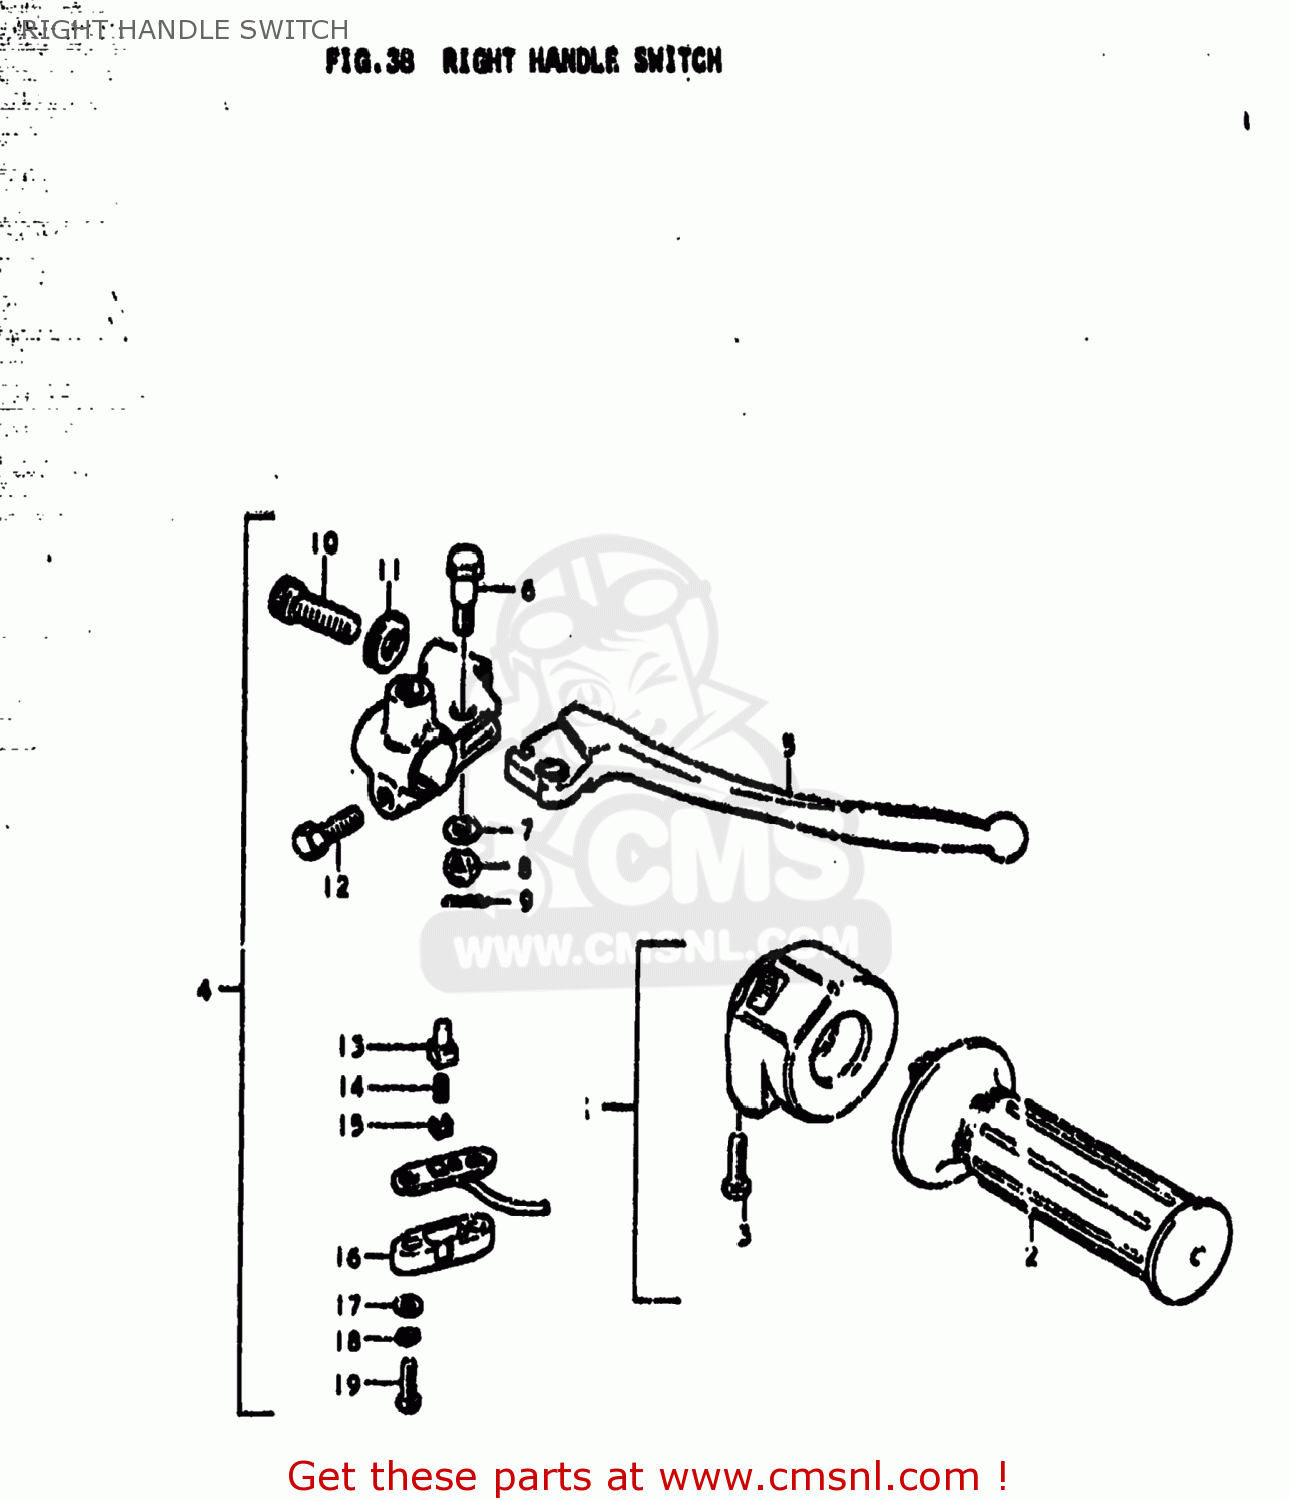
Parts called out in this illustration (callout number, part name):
1	GRIP ASSEMBLY,THROTTLE
2	GRIP,THROTTLE
3	SCREW
4	LEVER ASSEMBLY,BRAKE
5	LEVER,BRAKE
6	BOLT,LEVER
7	LOCK WASHER
8	NUT 6MM
9	COTTER PIN
10	ADJUSTER,CABLE
11	NUT,CABLE ADJUSTER
12	BOLT
13	HOLDER
14	SPRING
15	PLATE
16	COVER,FR BK TERMINAL BASE
17	WASHER
18	LOCK WASHER
19	SCREW
